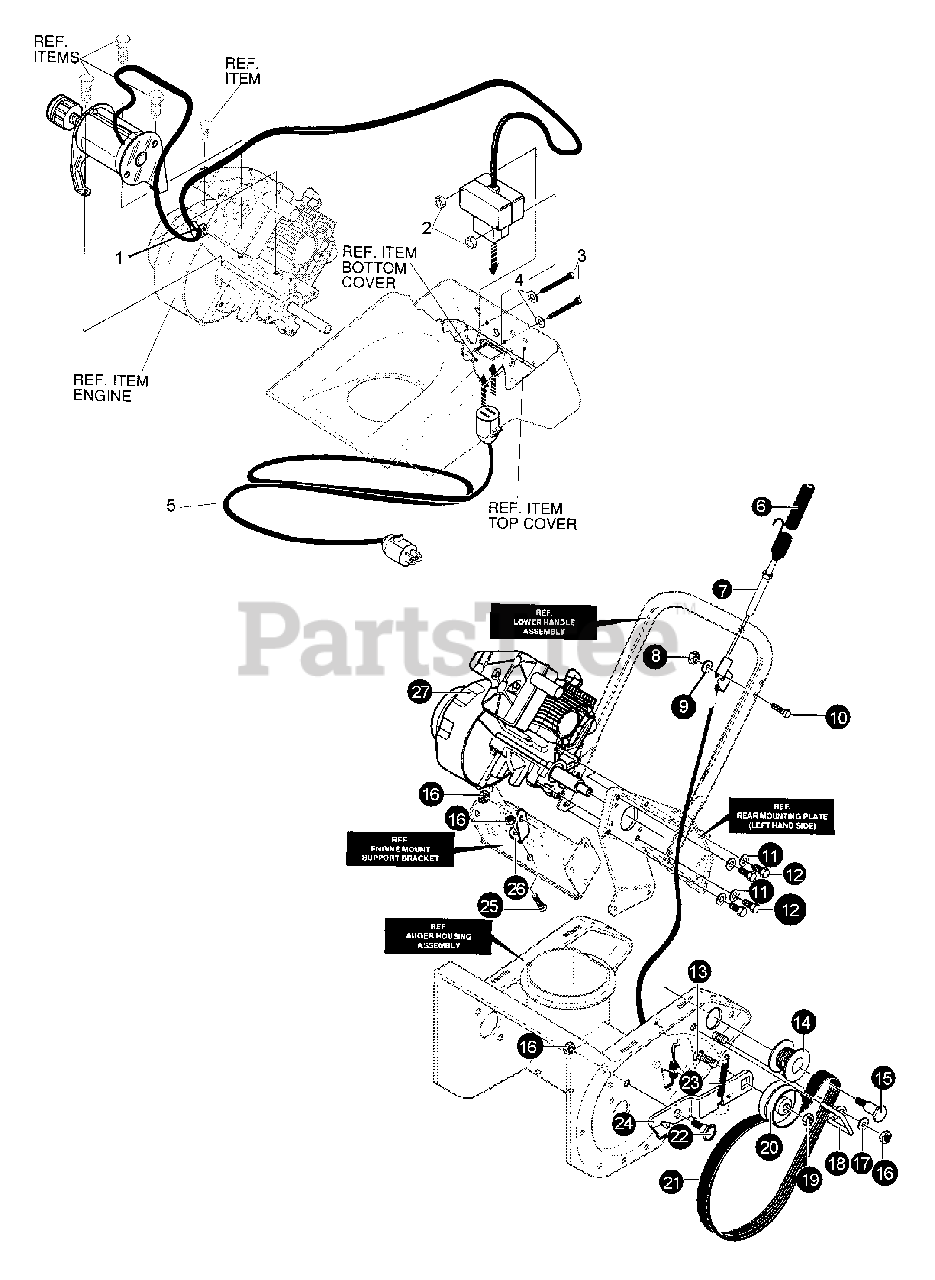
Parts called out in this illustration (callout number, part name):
1	RETAINER, WIRE
2	NUT - 8-32 -- KEPS
3	SCREW - 8-32 X 3"
4	WASHER - .188 X .38 X .040"
5	CORD, EXTENSION 10 FEET
6	COVER, CABLE HOLDER
7	CABLE, DRIVE CONTROL
8	NUT - 1/4-20
9	WASHER
10	SCREW - 1/4-20 X 1-1/2"
11	LOCKWASHER
12	SCREW - 5/16-18 X 3/4"
13	BOLT - 3/8-16 X 1-1/2"
14	PULLEY, 4.5 HP
15	BOLT, SHOULDER .625 X .282
16	NUT - 5/16-18
17	WASHER - .312 X .73 X .065
18	GUIDE, BELT 21"
19	LOCKNUT - 3/8-16
20	PULLEY, IDLER BB 1.88 OD
21	BELT, 10 RIB
22	BOLT, .500 X .177 HHSH 5/16-18
23	SPRING, IDLER BRAKE
24	BRACKET, IDLER ARM
25	SCREW - 5/16-18 X 1/2"
26	SUPPORT, ENGINE
27	ENGINE, 5.0 HP
